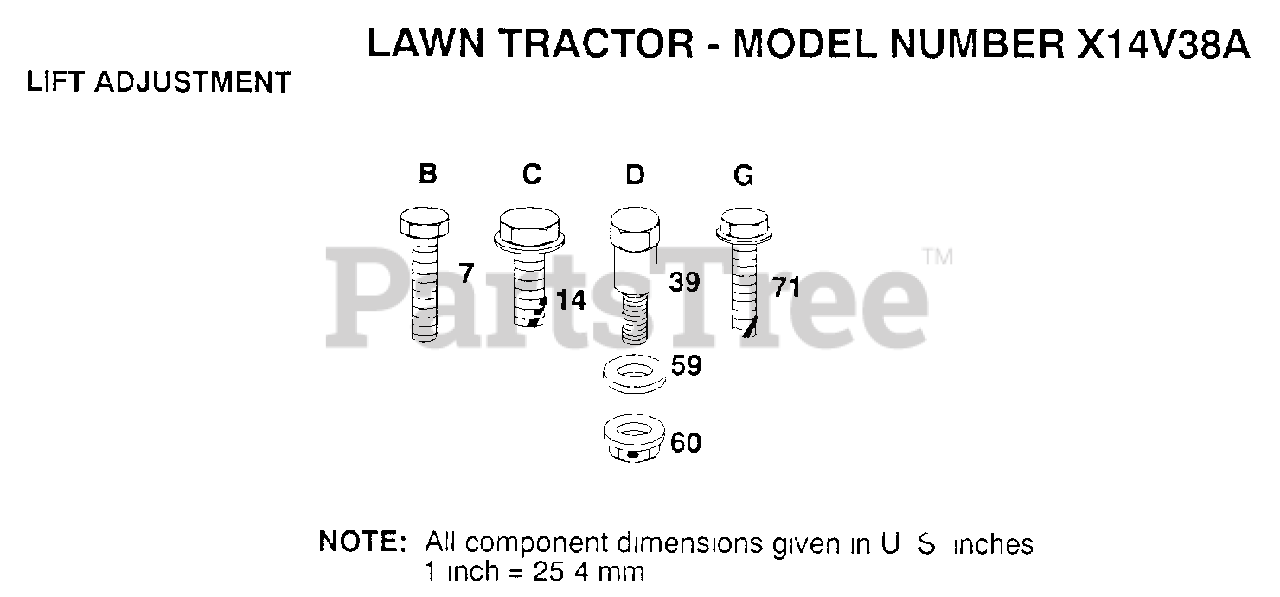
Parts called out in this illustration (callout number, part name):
7	SCREW
14	SCREW HEX CRT
39	"BOLT, SHOULDER LT"
59	WASHER T
60	NUT SPECIAL T
71	SCREW
